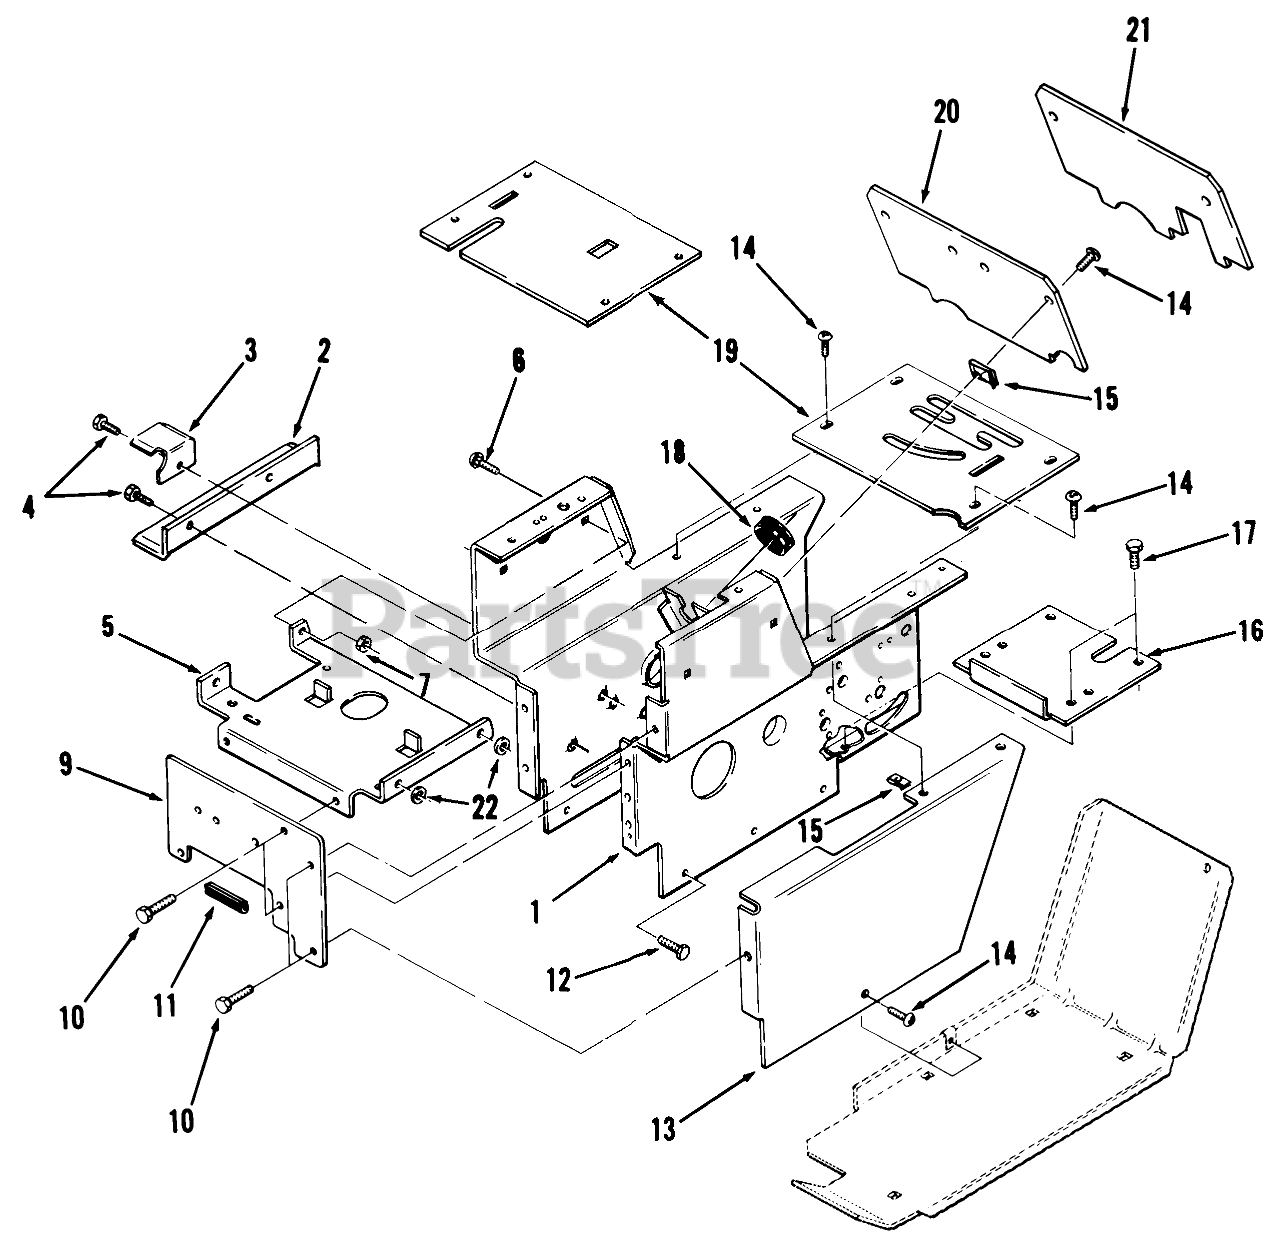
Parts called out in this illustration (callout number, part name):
1	Hoodstand
2	ANGL-BLT GURDB
3	Belt Bracket
3	BRCKET-BLT SUTB
4	SCREW
5	SUPPORT-BATTERY B
6	CARRIAGE BOLT -4
7	Nut
9	Front Plate
10	SCREW
11	EDGE TRIM 2" 102896
12	SCREW
13	Side Cover LH
14	Screw
16	Cover-Dust
17	SCREW
18	GROMMET
19	PLATE-SHIFT PATTE B
19	PLATE - SHIFT
20	PLATE-HOODSTAND REAR
21	PLATE-HOODSTAND REAR
22	Washer
